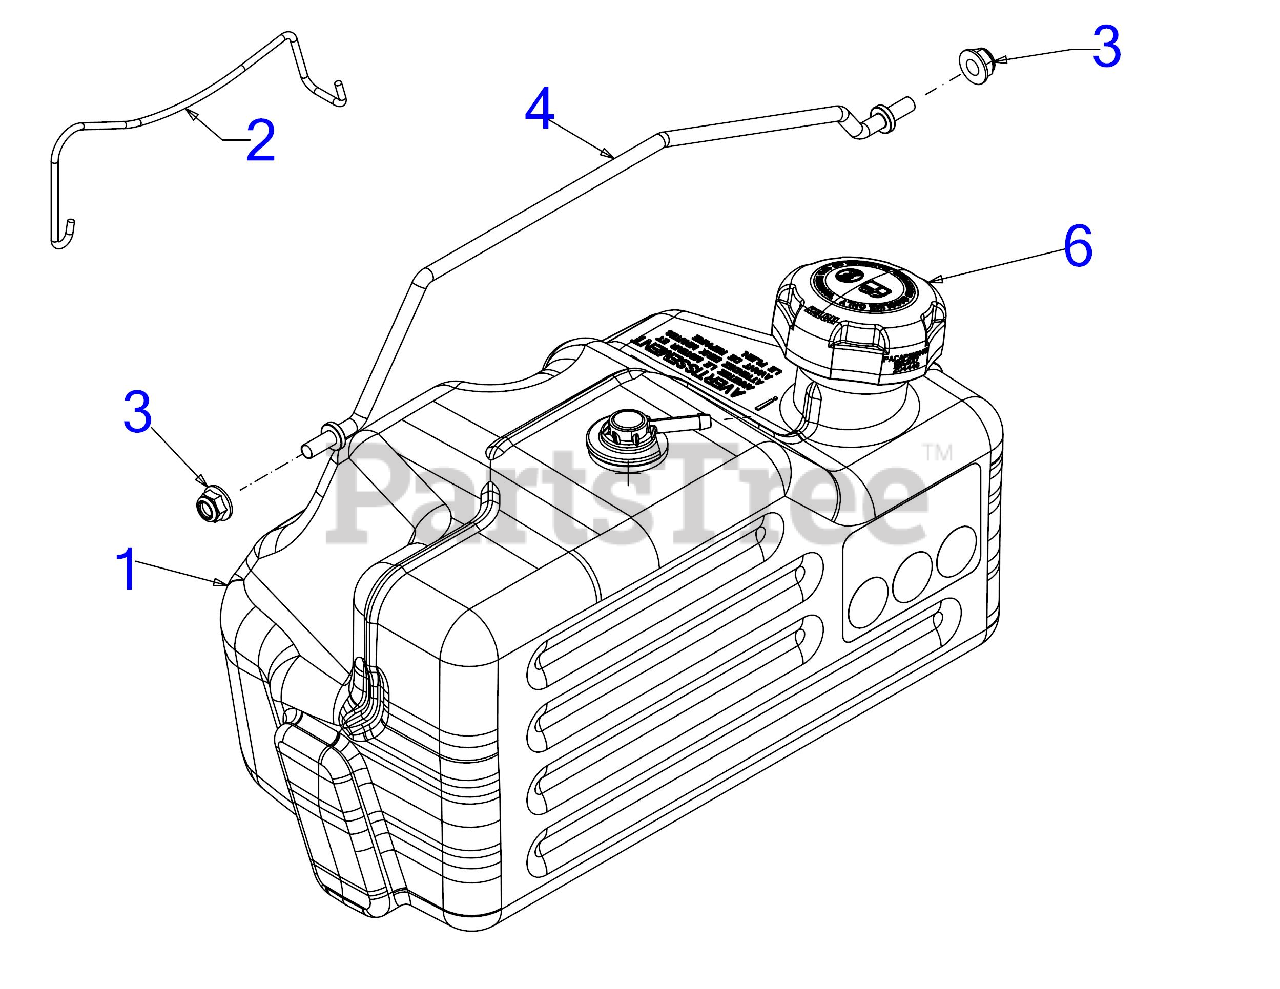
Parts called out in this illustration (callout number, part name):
1	FUEL TANK ASSEMBLY
2	BATTERY ROD ASSEMBLY
3	FLANGE LOCK NUT 5/16-18
4	FUEL TANK CLAMP ROD
6	FUEL CAP W/TETHER
